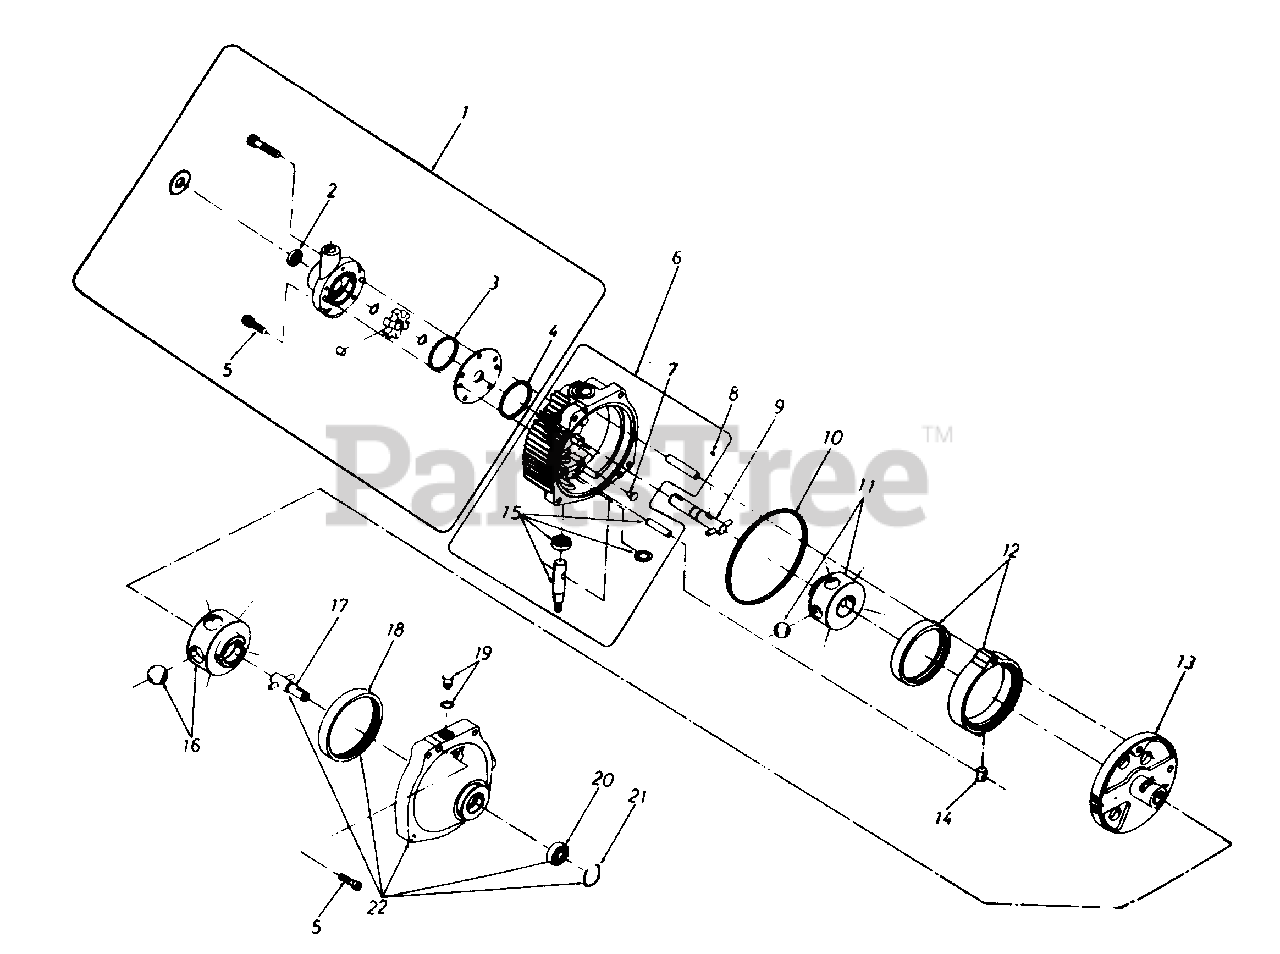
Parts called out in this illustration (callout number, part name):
1	Charge Pump Kit
2	Oil Seal
3	Square Cut Seal Ring .036
4	Square Cut Seal Ring .038
5	Socket Head Cap Screw 5/16-18 x 1.25" Long
6	Cover Subassembly
8	Drive Pin
9	Input Shaft Subassembly
10	Square Cut Seal Ring .166
11	Pump Rotor--Ball Subassembly
12	Cam Ring Subassembly
13	Pintle Subassembly
14	Cam ring Insert
15	Control Shaft Kit
16	Motor Rotor--Ball Subassembly
17	Output shaft Subassembly
18	Motor Race
19	"O"-Ring Plug Subassembly
20	Ball Bearing (Output)
21	Retaining Ring
22	Body Subassembly
